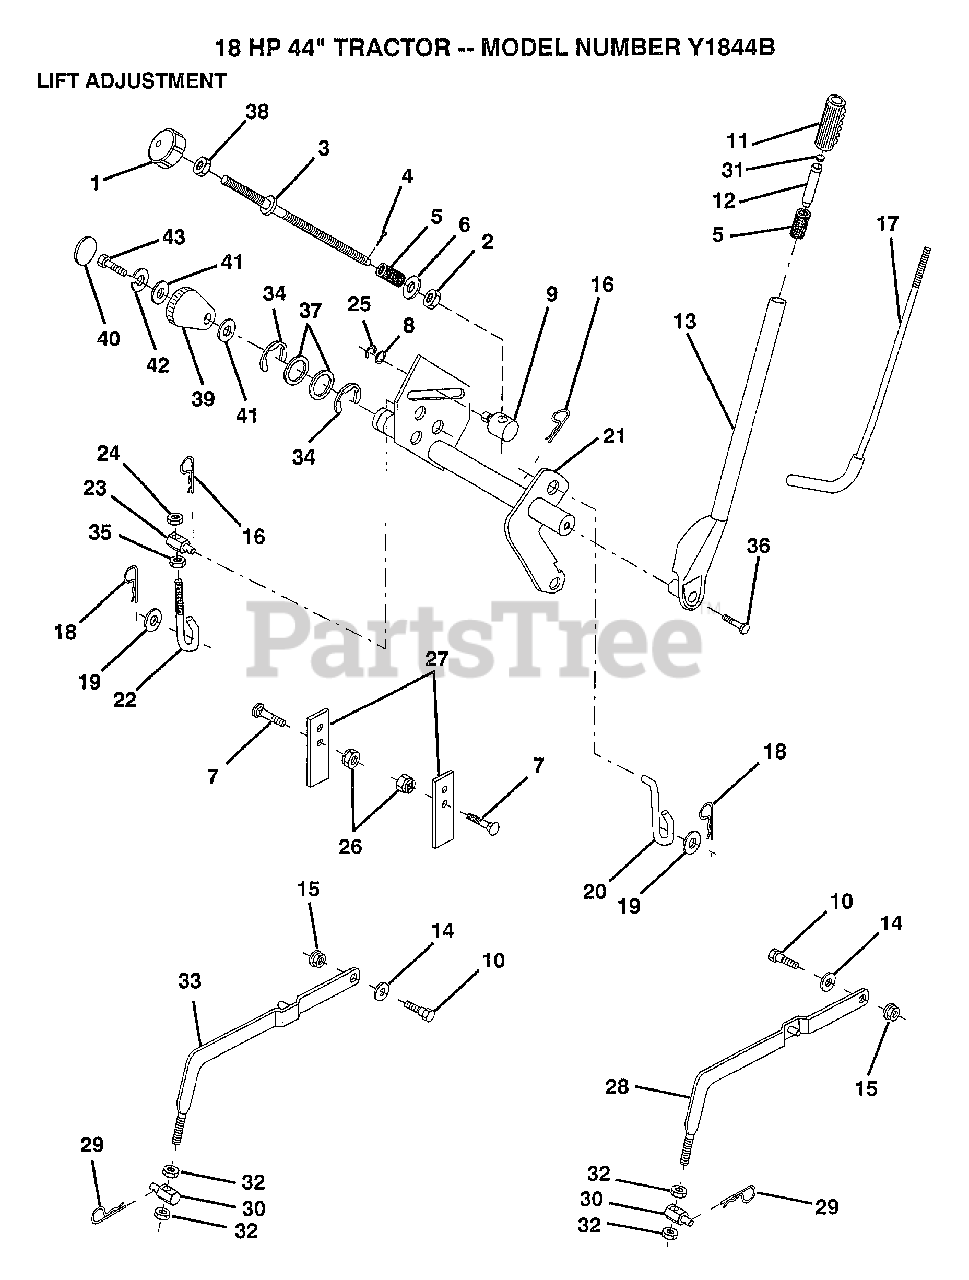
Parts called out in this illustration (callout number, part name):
2	NUT T
3	ROD LIFT LT
5	SPRING T
6	WASHER
8	WASHER
9	TRUNION LT
10	"BOLT, SHOULDER LT"
11	GRIP
14	WASHER T
15	NUT SPECIAL T
17	LEVER ROD LT
18	SPRING.RETAINER
20	LIFT LINK LT
22	PIVOT PIN T
25	KLIP RING
27	UPSTOP
28	RH SUSP ARM ASM
29	SPRING H
32	NUT
33	LH SUSP ARM ASM
34	E-RING
35	NUT
36	"BOLT,HEX"
37	WASHER
38	NUT
39	HEIGHT INDICATOR
40	"PLUG,HOLE"
41	WASHER
42	LOCKWASHER
